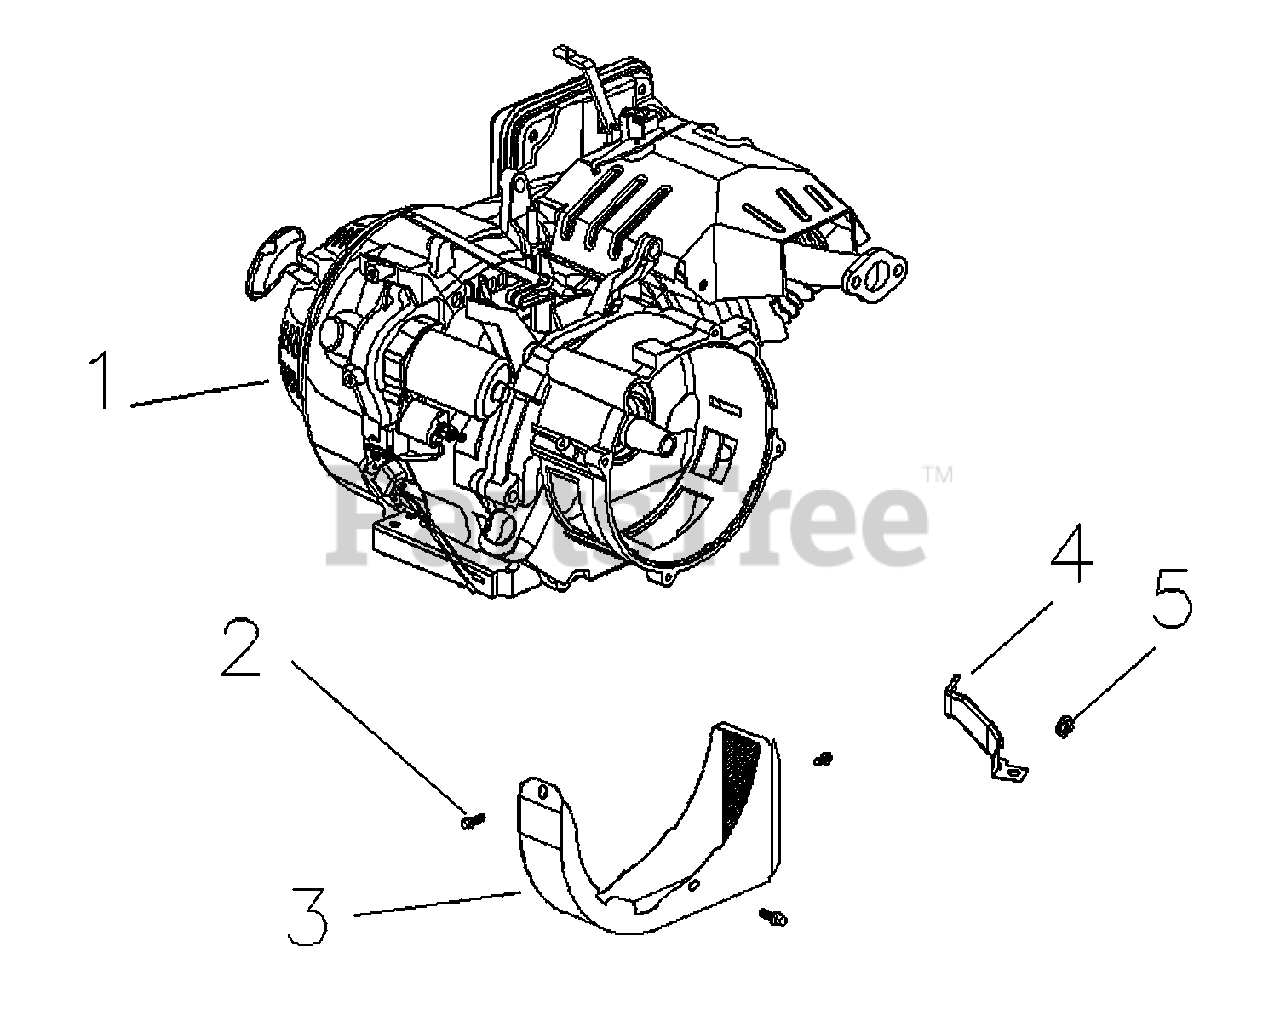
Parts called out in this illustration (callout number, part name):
1	ENGINE G390FA
2	SCROLL' HONEYWELL
3	BOLT' FLANGE M5*10
4	BRACKET'AIR CLEANER
5	NUT' FLANGE M6
